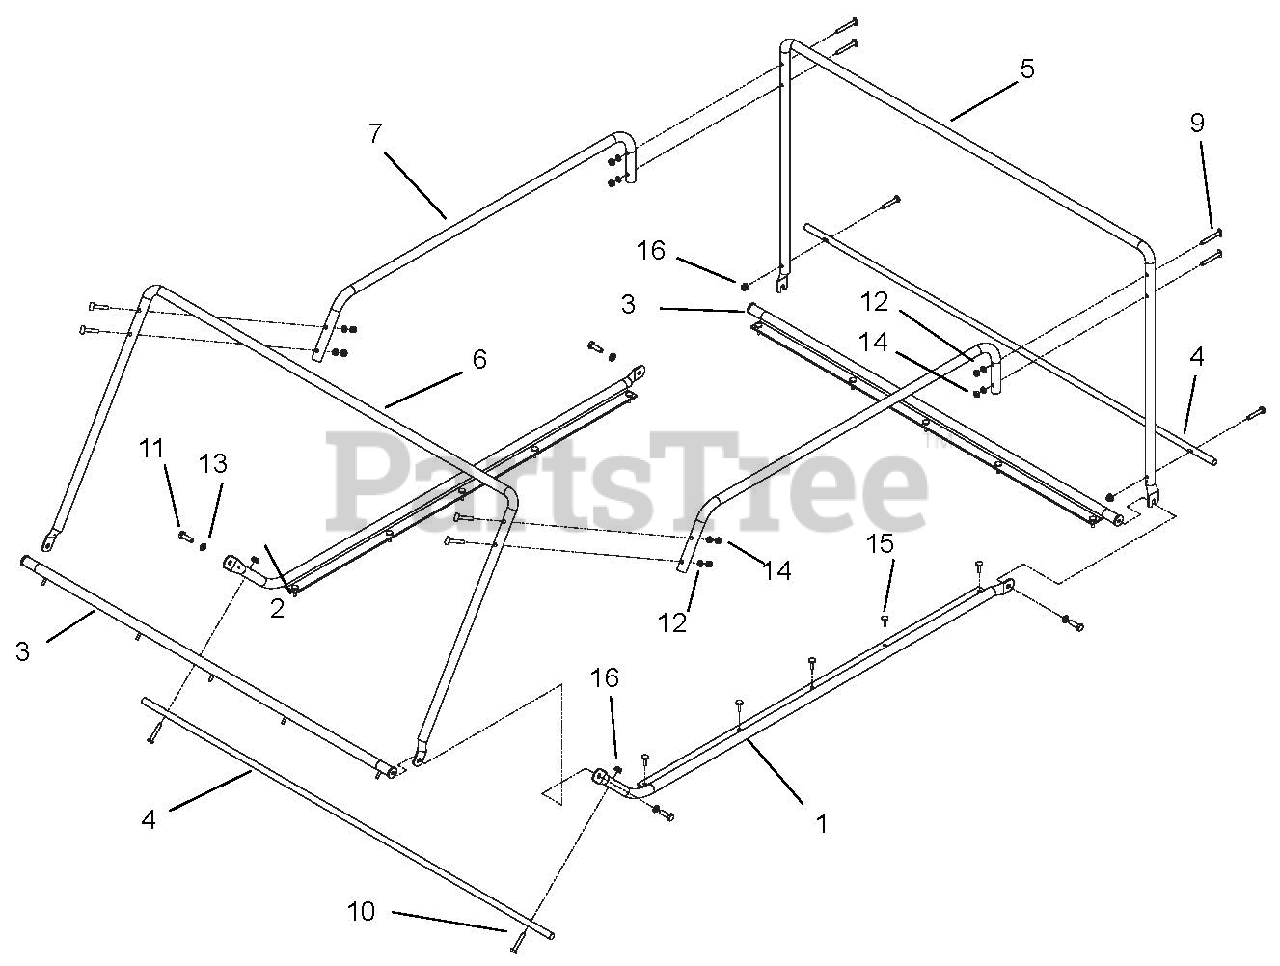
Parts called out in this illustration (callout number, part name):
1	Basket Clamp Assembly
2	Basket Clamp Assembly
3	Basket Clamp Assembly
4	Support Rod
5	Rear Upright
6	Front Upright
7	Frame Basket Side Top
9	Bolt, 1/4-20 x 2.0 Contour Head
10	Bolt, Hex 1/4-20 x 1.5 Grade 5
11	Bolt, Hex 5/16-18 x 1.00 Grade 5
12	Washer, Lock .25 x .062 YWZC
13	Washer, Lock .31 x .078 YWZC
14	Nut, Hex 1/4-20
15	Rivet, Bulb Tite
16	Nut, Nylock Flange .25-20
